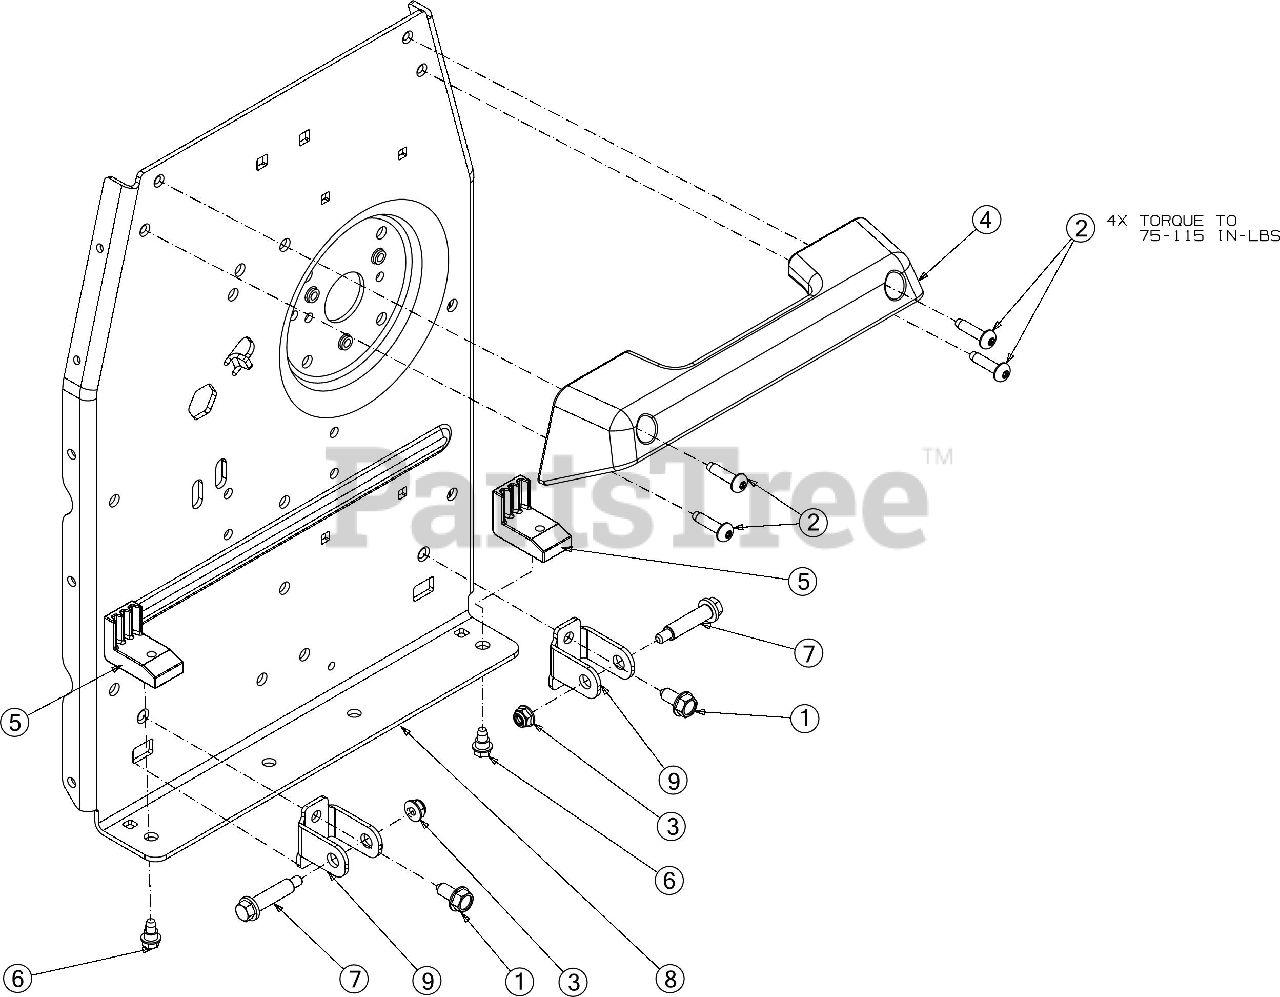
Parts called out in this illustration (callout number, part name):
1	SCREW 5/16-18 x .750
2	SCREW 1/4-20 x 1.0
3	FLANGE LOCK NUT
5	BUMPER PAD
6	SHOULDER SCREW 1/4-20 x .50
7	SHOULDER SCREW
8	FRAME MOUNT BRACKET
9	SUPPORT BRACKET
